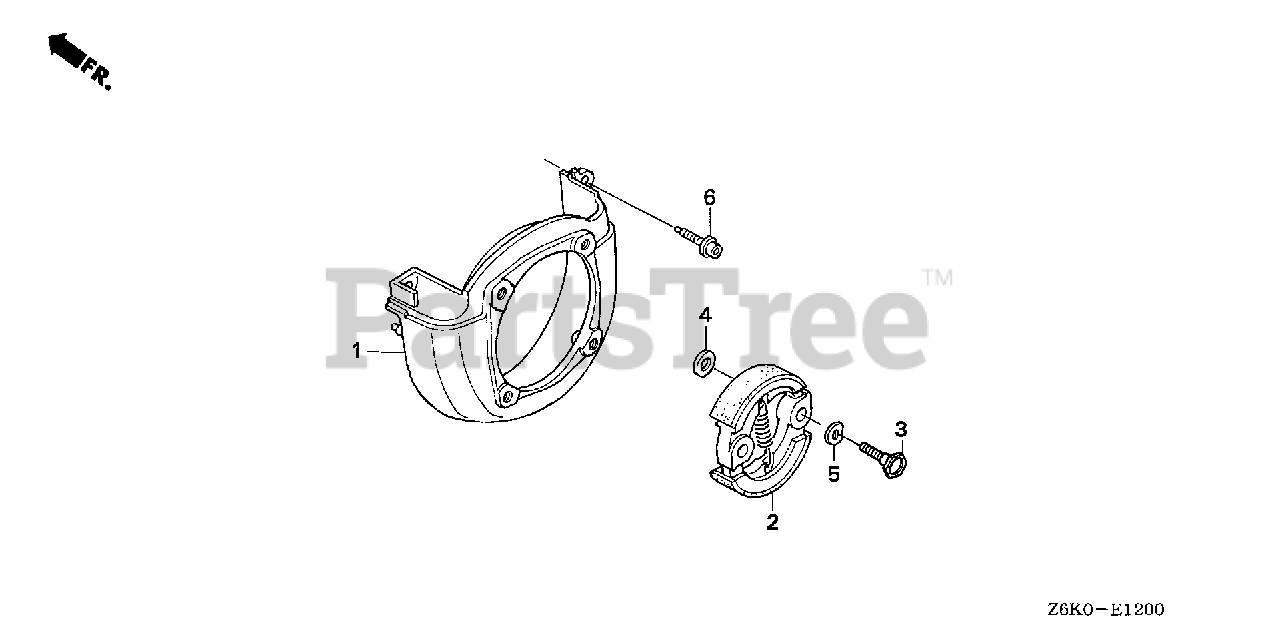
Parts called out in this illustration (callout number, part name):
1	COVER, FAN
2	CLUTCH ASSY. (ACRO)
3	BOLT, CLUTCH (8MM)
4	WASHER, CLUTCH (8X17)
5	WASHER, WAVE (10MM)
6	BOLT, SOCKET (5X20)
